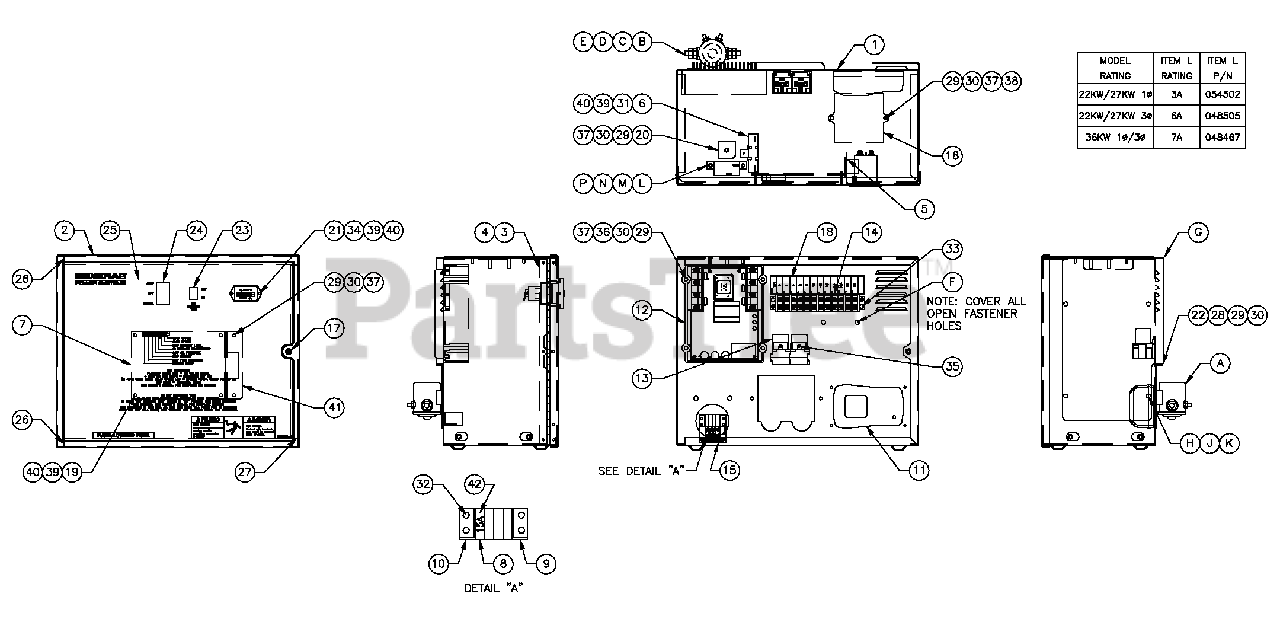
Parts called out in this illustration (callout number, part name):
1	ENCL HSB CONTROL PANEL
2	COVER CONTROL PANEL R-200B
3	HINGE CONTINUOUS H-PANEL
4	RIVET POP .125 X .275 SS
5	SCREW PPPH HI-LO #4-24 X 3/8
6	WASHER FLAT M3
7	ASSY PCB R-200B CNTRL 1800
8	HOLDER FUSE WICKMANN 178.6150
9	ADPTR RH SIDE WICKMANN 178.6191
10	ADPTR LH SIDE WICKMANN 178.6192
11	BATC 13.4VDC 2.5A W/4POS PLUG
12	ASSY PCB HI-PWR VOLTAGE RGLTR
13	RELAY 12VDC C FORM W/DIODE
14	BLOCK TERM 20A 12 X 6 X 1100V
15	DECAL CPL CNT PNL FUSES
16	ASSY PCB BOSCH GOV DRIVER
17	M5X0.8 CAPTIVE PANEL KNLD HD
18	DECAL CPL 3.9L TB1
19	SPACER 9.5H 3.2 ID
20	DIO BRIDGE 25A 600V
21	HOUR METER 10-80VDC
22	PLATE HARNESS CLAMP
23	SWITCH RKR DPST 125V SPD
24	SWITCH RKR DPDT ON-OFF-ON
25	DECAL CONTROL FLEX R-200B
26	SEAL COVER 3.18X12.7X382
27	SEAL COVER 3.18X12.7X283
28	SCREW HHPM M5-0.8 X 12
29	WASHER FLAT M5
30	WASHER LOCK M5
31	RES WW 15R 5% 25W QK CONN
32	SCREW PHTT M3.5-0.6 X 10
33	SCREW PHTT M3.5-0.6 X 16
34	SCREW PHM M3-0.5 X 10 BLACK
35	SCREW PHTT M4-0.7 X 10 ZYC
36	SCREW PPHM M5-0.8 X 50 ZNC
37	NUT HEX M5-0.8 G8 YEL CHR
38	SCREW PPHM M5-0.8 X 30 SS
39	WASHER LOCK M3
40	NUT HEX M3-0.5 G8 YEL CHR
41	SUPPORT ANGLE PCB
42	FUSE ATO TYPE 15 AMP (BLUE)
A	RELAY SOLENOID 12VDC PNL MNT
B	SCREW HHC 1/4-20 X 3/4 G5
C	WASHER FLAT 1/4-M6 ZINC
D	WASHER LOCK M6-1/4
E	NUT HEX 1/4-20 STEEL
F	SEAL WEATHER .45"DIA
G	COVER CONTROL PANEL SIDE
H	SCREW PPHM M5-0.8 X 12 ZNC
J	WASHER LOCK M5
K	WASHER FLAT M5
L	DPE BREAKER
M	WASHER FLAT M3
N	WASHER LOCK M3
P	NUT HEX M3-0.5 G8 YEL CHR
